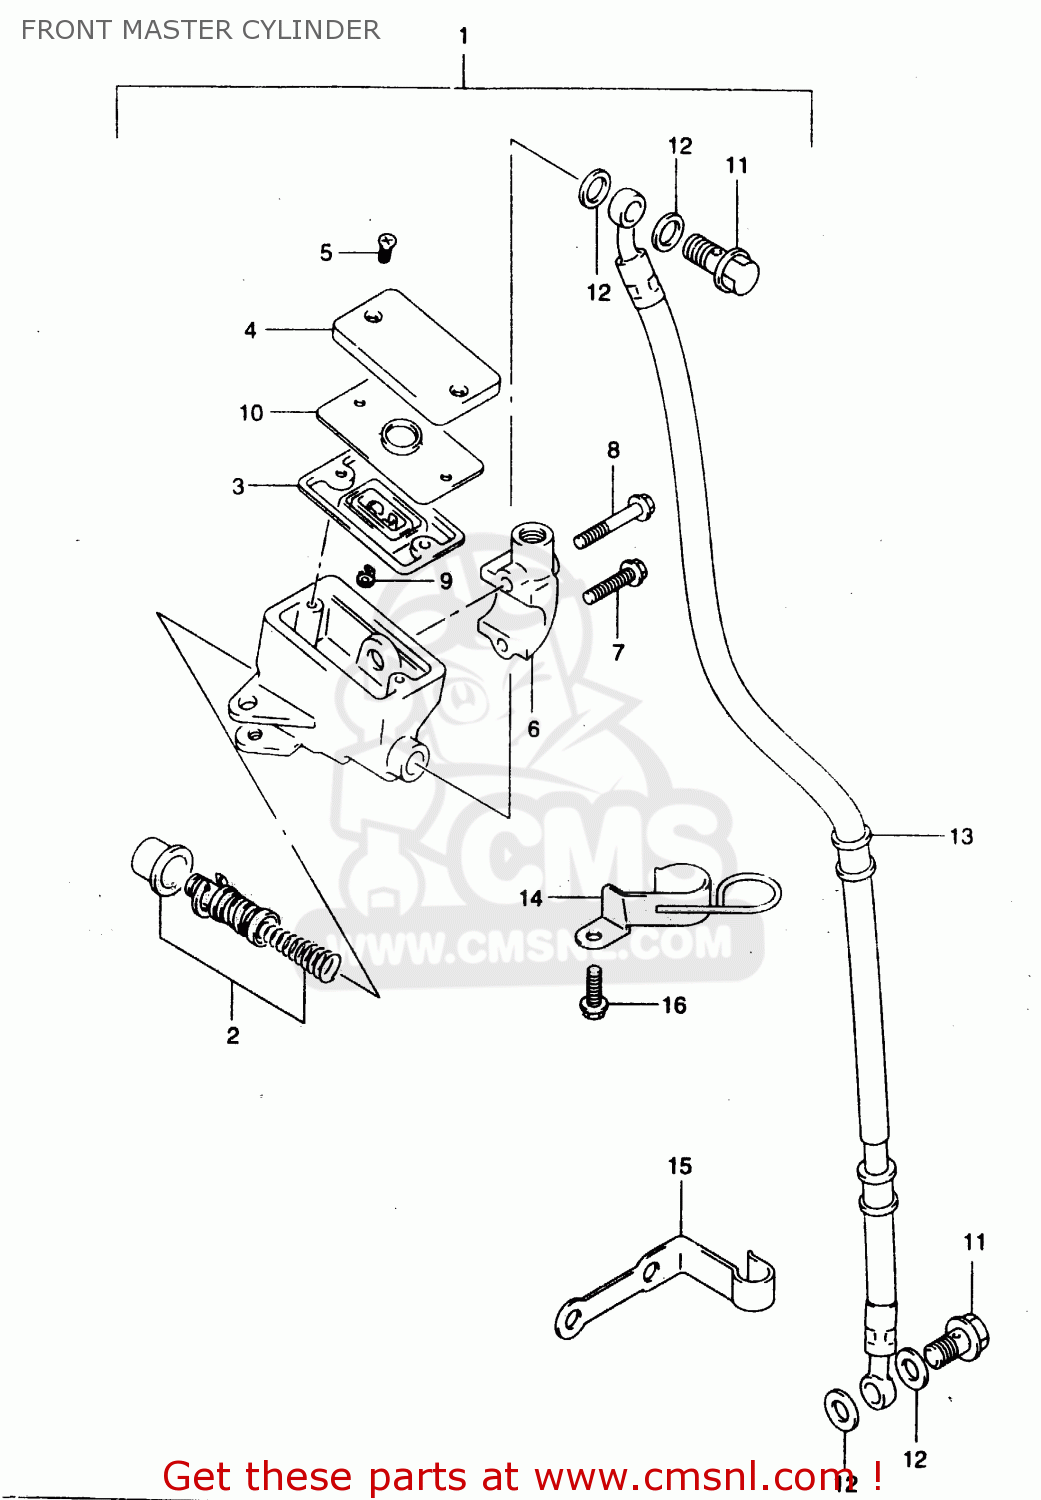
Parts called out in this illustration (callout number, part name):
1	CYLINDER ASSY,FR MASTER
2	PISTON/CUP SET
3	4
4	CAP
5	SCREW
6	HOLDER
7	BOLT(6X25)
8	BOLT(6X38)
9	PROTECTOR
10	PLATE,DIAPHRAGM
11	BOLT UNION
12	WASHER(10X15X1.5)
13	HOSE,FR BRAKE
14	CLAMP,FR BRAKE HOSE
15	CLAMP,BRAKE HOSE
16	BOLT
